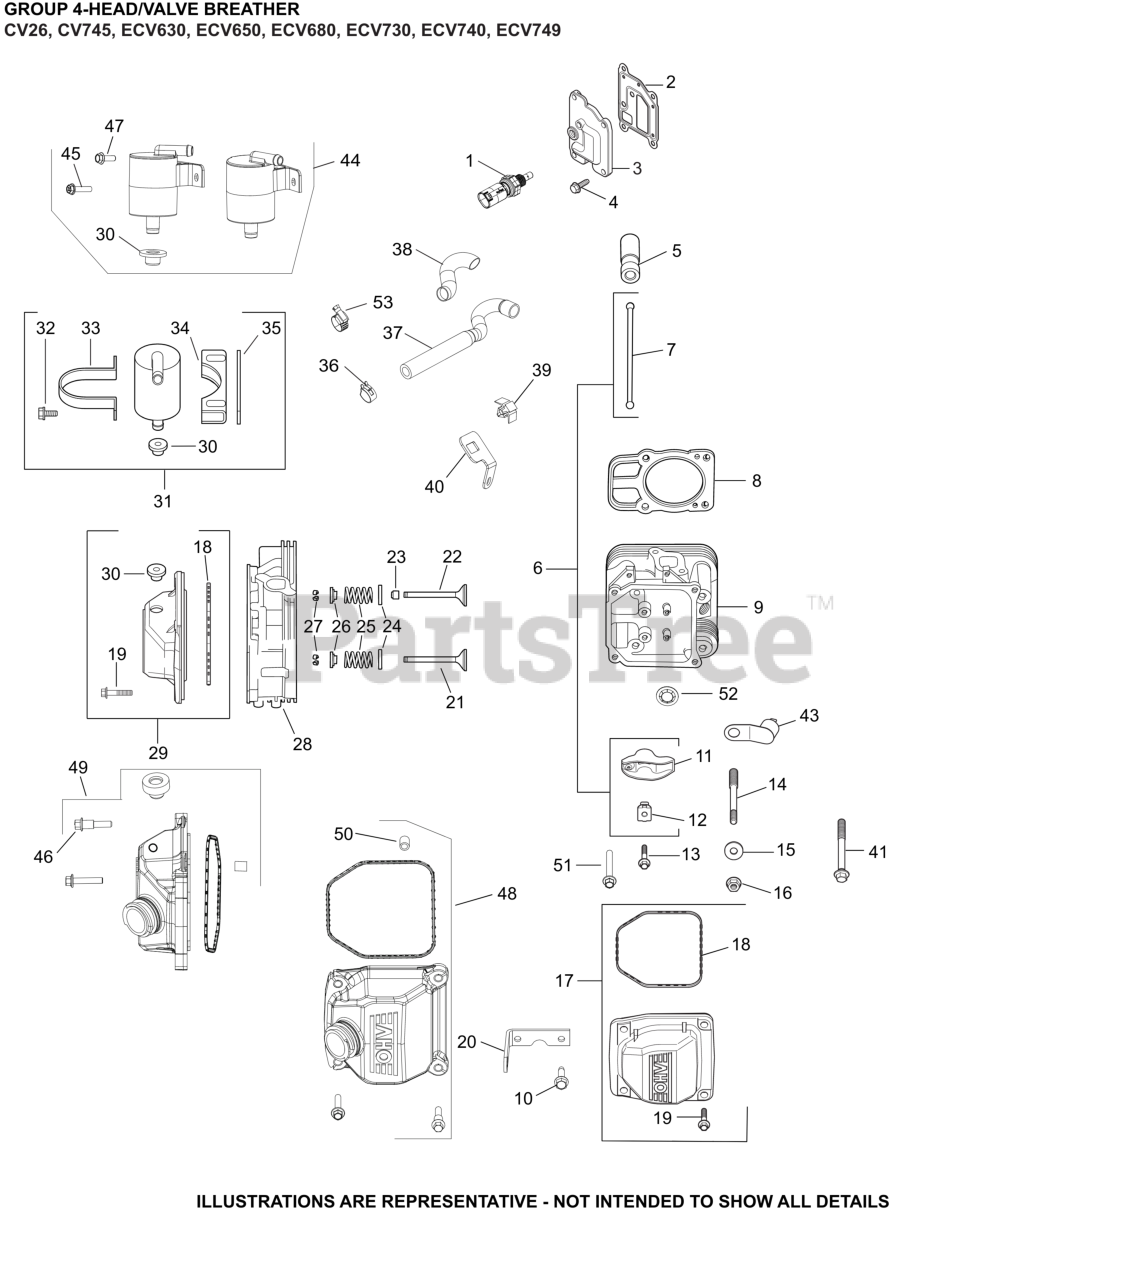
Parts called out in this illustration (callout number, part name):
1	SENSOR, TEMPERATURE
2	GASKET, BREATHER
3	KIT, BREATHER COVER
4	SCREW, THREAD FORMING
5	LIFTER, VALVE HYDRAULIC-USE 25 351 11-S
6	KIT, VALVE TRAIN
7	ROD, PUSH
8	KIT, GASKET CYLINDER HEAD
9	KIT, CYLINDER HEAD (#2)-(#2481804S)
11	ARM, ROCKER
12	PIVOT, ROCKER ARM
14	STUD, M8X1.25
15	WASHER, FLAT 8.6 MM
16	NUT, FLG M8X1.25
17	KIT, VALVE COVER-PLAIN (PLASTIC)
18	O-RING (YELLOW), VALVE CO
19	SCREW, FLG M6X1.0X30-USE 25 086 797-S
20	STRAP, LIFT-USE 25 445 06-S
21	VALVE, EXHAUST
21	VALVE, EXHAUST (.25)
22	VALVE, INTAKE (STD)
22	VALVE, INTAKE (.25)-(#DSC)
23	SEAL, VALVE BAND
24	RETAINER, SPRING
25	SPRING, VALVE
26	KIT, RETAINER
27	CAP, VALVE SPRING
28	KIT, CYLINDER HEAD (#1)-(#2481803S)
29	KIT, VALVE COVER
30	GROMMET, RUBBER
37	HOSE, BREATHER
38	SLEEVE, ANTI ABRASION-USE 25 431 12-S
39	CLIP, O2 SENSOR
40	BRACKET, OXYGEN SENSOR
44	KIT, BREATHER SEPARATOR
47	SCREW, HI-LOW
52	RETAINER, VALVE GUIDE (KM)
54	SCREW, HEX FLANGE
